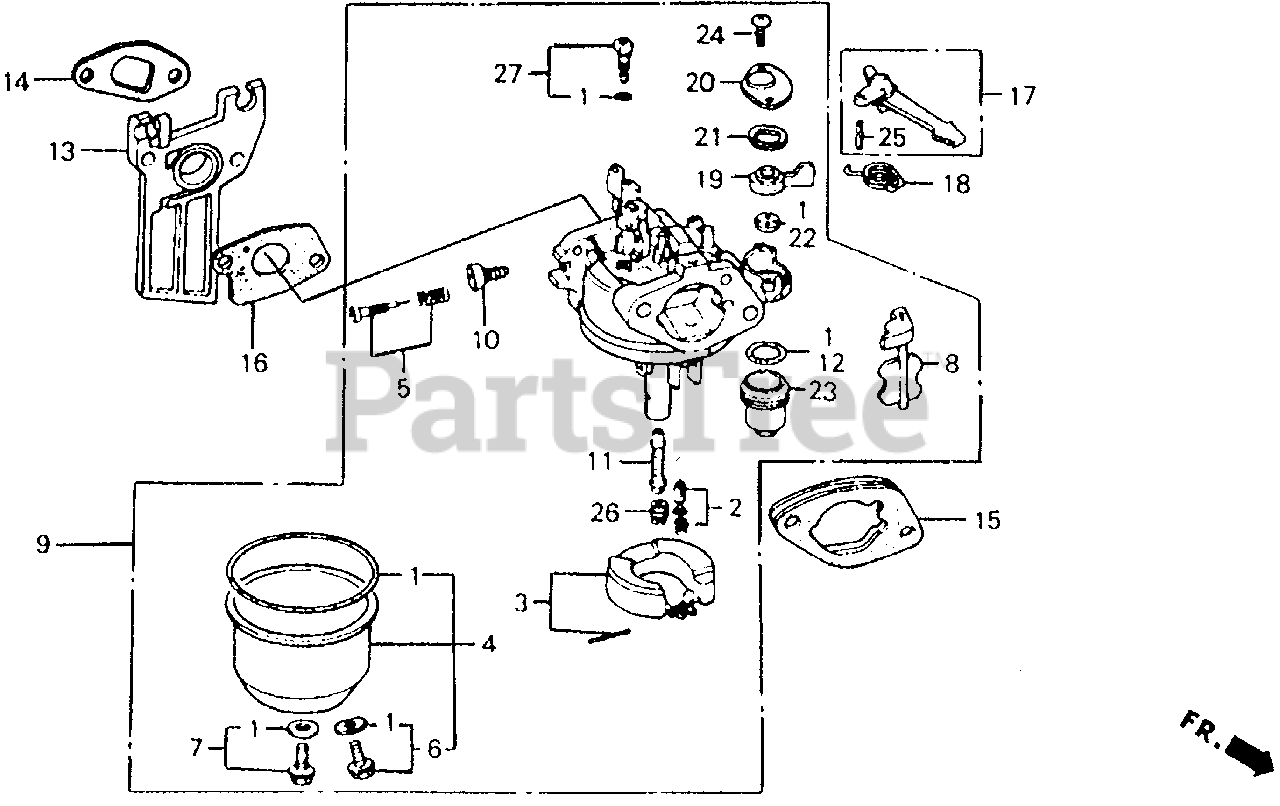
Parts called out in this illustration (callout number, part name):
1	GASKET SET
1	GASKET SET (NOT AVAILABLE)
2	VALVE SET, FLOAT
3	FLOAT SET
4	CHAMBER SET, FLOAT
5	SCREW SET, PILOT
6	SCREW SET, DRAIN
7	SCREW SET B
8	CHOKE SET
9	CARBURETOR ASSY. (BE01A D)
9	CARBURETOR ASSY. (BE01D B)
9	CARBURETOR ASSY. (BE01D C)
9	CARBURETOR ASSY. (BE01D D)
9	CARBURETOR ASSY. (BE01D E) (NOT AVAILABLE)
9	CARBURETOR ASSY. (BE01D G)
9	CARBURETOR ASSY. (BE01D H)
10	SCREW, THROTTLE STOP
11	NOZZLE, MAIN (NOT AVAILABLE)
11	NOZZLE, MAIN
12	GASKET, FUEL STRAINER CUP
13	INSULATOR, CARBURETOR
14	GASKET, INSULATOR
15	SPACER, CARBURETOR
16	GASKET, CARBURETOR
17	LEVER, CHOKE (STD)
18	SPRING, RETURN
19	LEVER, VALVE
20	PLATE, LEVER SETTING
21	SPRING, VALVE LEVER
22	GASKET, VALVE
23	CUP, FUEL STRAINER
24	SCREW, PAN (3X8)
25	PIN, SPRING (2X12)
26	JET, MAIN (#55)
26	JET, MAIN (#58)
26	JET, MAIN (#60)
26	JET, MAIN (#62)
27	JET SET, PILOT (#35)
